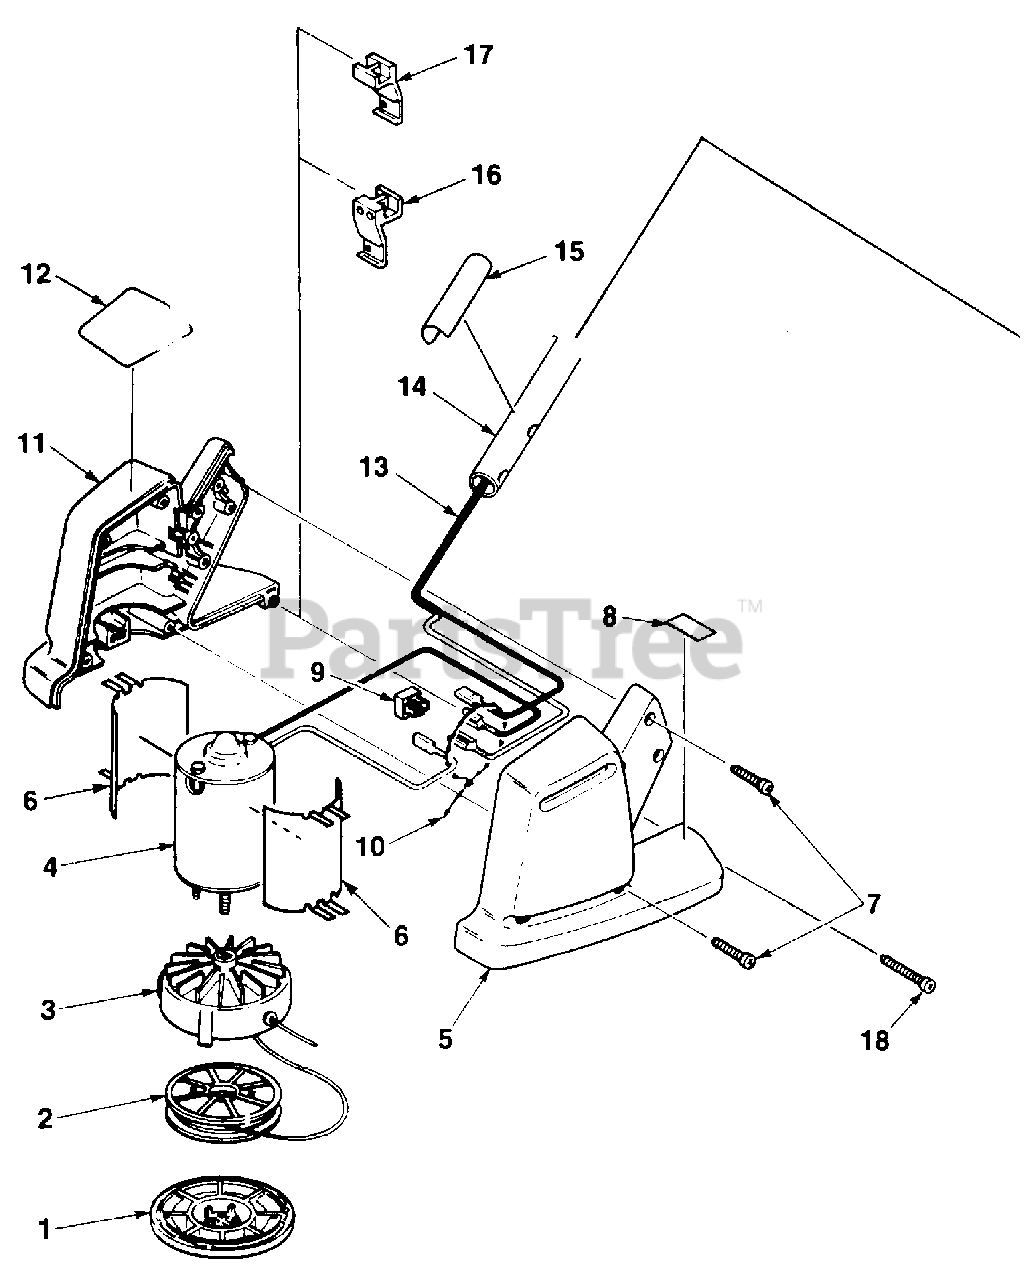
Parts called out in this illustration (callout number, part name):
1	RETAINER SPOOL
2	SPOOL & STRING
3	HEAD- String
4	MOTOR- Electric 120V (ST-40)
5	HOUSING- Motor (left) (ST-40)
6	SHIM- Motor
7	SCREW- Thread forming 10-16 x 3/4
8	DECAL- Warning
9	RECTIFIER
10	CLAMP- Wire
11	HOUSING- Motor (right) (ST-40)
12	DECAL (ST-40)
13	CABLE- Electrical
15	DECAL- Warning
16	CUT- OFF- String (ST-40)
17	CUT- OFF- String (ST-60)
18	SCREW- Thread forming (10 x 1")
